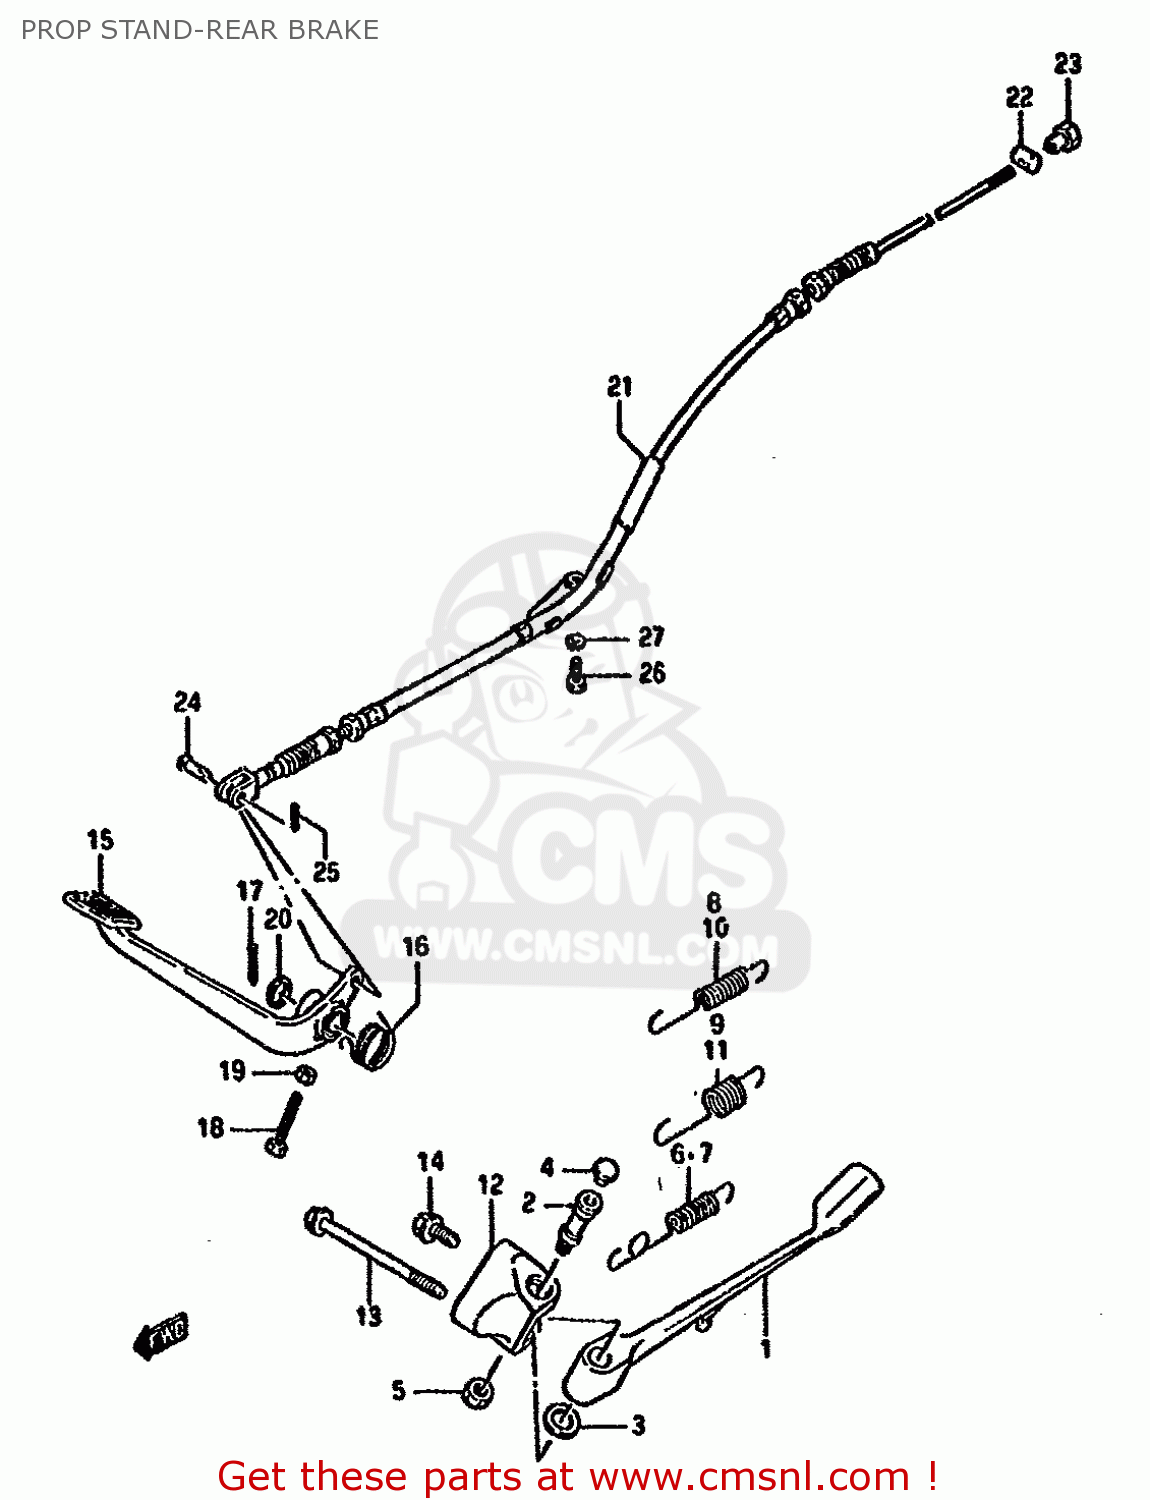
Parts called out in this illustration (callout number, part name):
1	STAND,PROP
2	BOLT,PROP STAND
3	THRUST WASHER
4	CAP,PROP STAND BOLT
5	NUT
6	SPRING
7	SPRING
8	SPRING
9	SPRING
10	SPRING
11	SPRING
12	BRACKET,PROP STAND
13	BOLT(10X105)
14	BOLT 10X25
15	PEDAL,BRAKE
16	SPRING
17	COTTER PIN
18	BOLT
19	NUT 6MM
20	WASHER (16.5X42X2.6)
21	CABLE,RR BRAKE
22	PIN
23	NUT (6MM)
24	PIN(L:17.5)
25	PIN
26	BOLT 6X16
27	WASHER,LOCK
